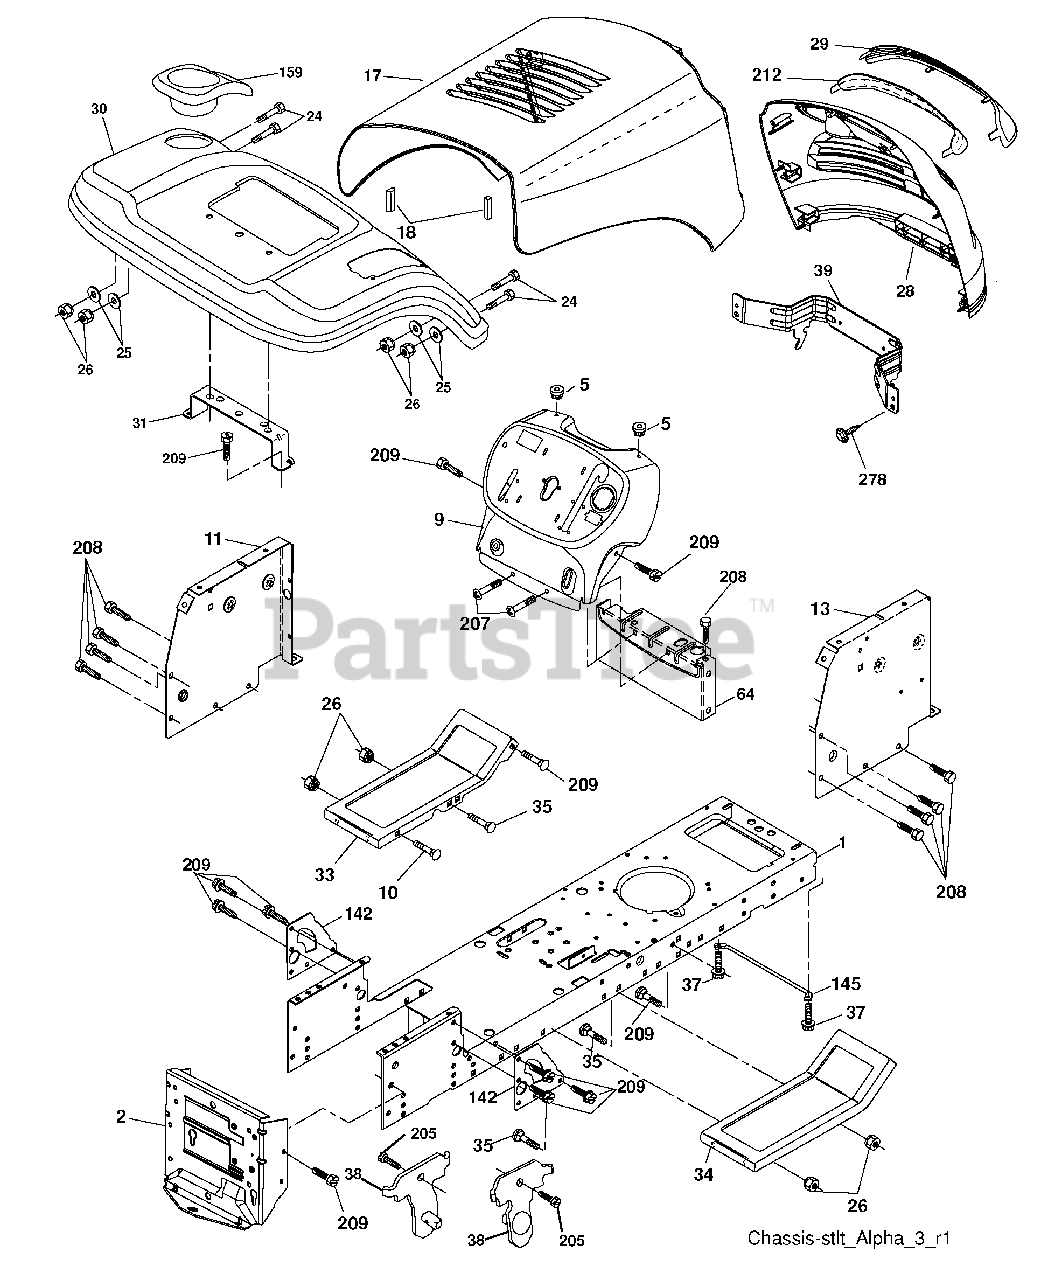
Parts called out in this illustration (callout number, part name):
1	Chassis
2	Drawbar, Stretch
5	Bumper, Hood/Dash
9	Dash
10	Bolt, Carriage 3/8-16 x 1
11	Panel Dash LH
13	Panel Slkscr Dash RH
17	Hood
18	Bumper Hood
24	Bolt Fin Hex 3/8-16 unc x 1 Gr. 5
25	Washer 13/32 x 13/16 x 12 Ga.
26	Nut Lock Hex w/Ins 3/8-16 unc
28	Grille
29	Lens Grille Bar
30	Fender
31	Bracket Fender Repl 109873X
33	Footrest Pnt LH
34	Footrest Pnt RH
35	Bolt Rdhd Sht Sqnk 3/8-16 x 3/4
37	Screw Thdrol 5/16-18 x 1/2 TYT
38	Bracket Asm. Pivot Mower
39	Bracket Pivot
64	Dash Lower
142	Plate Reinforcement
145	Rod Pivot Chassis/Hood
159	Cupholder
205	Screw Thdrol 3/8-16 x 1/2
207	Screw 5/16-18 x 1/2
208	Screw Thdrol 3/8-16 x 1/2
209	Screw Hex Wsh Thdrol 3/8-16
212	Insert Lens Reflect
278	Screw #10 x 0.750 BOS Thread
278	Plug Button Blk 359 Dia Choke
278	Plug Dome Plastic
